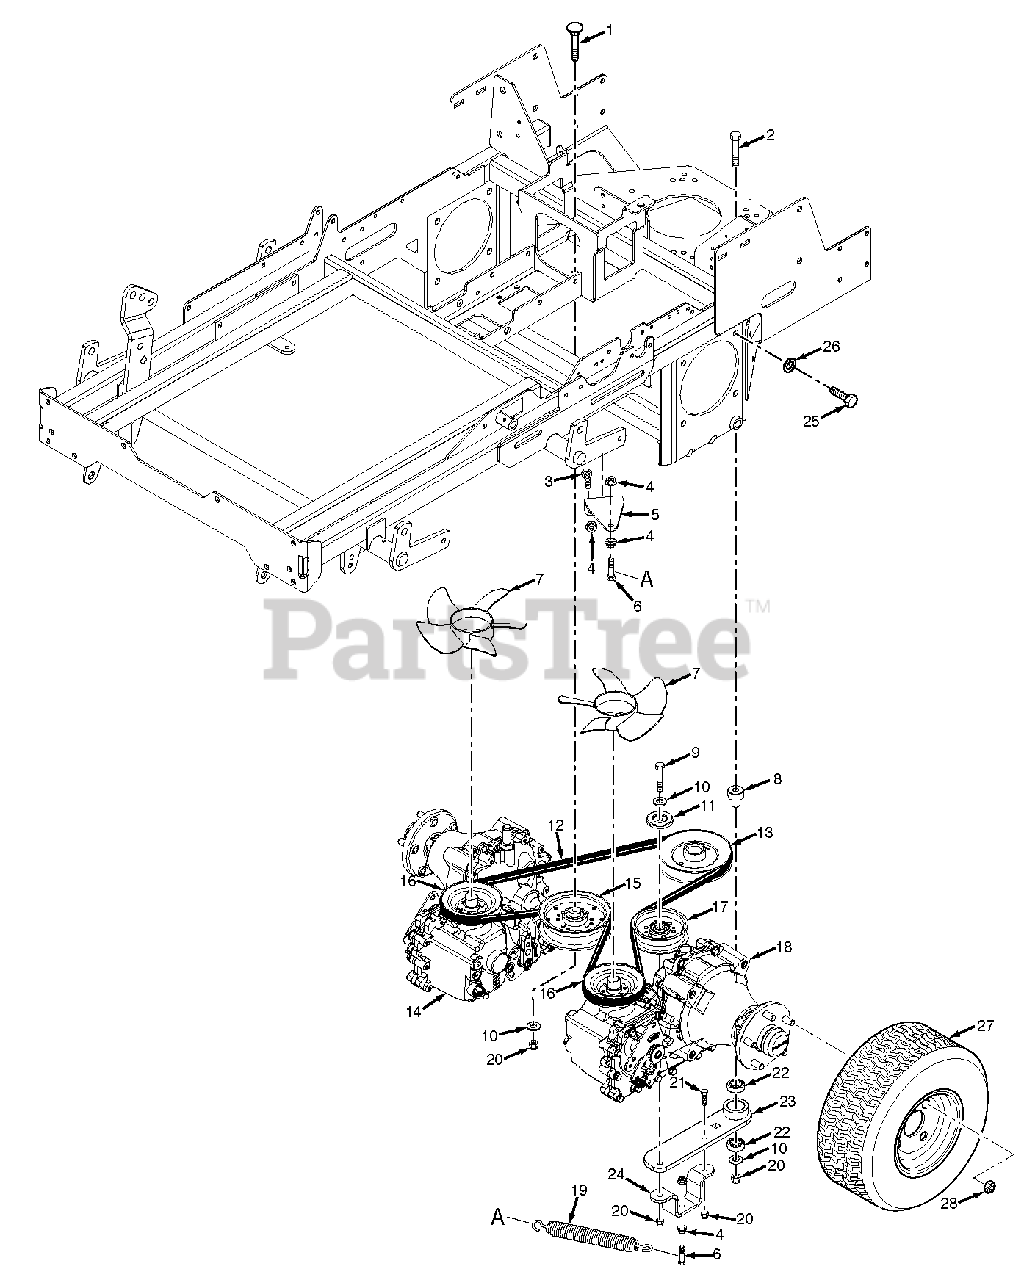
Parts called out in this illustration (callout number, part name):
1	Bolt, Carriage 3/8-16 x 2-1/2"
2	Bolt, Hex Head 3/8-16 x 3"
3	Bolt, Hex Head 3/8-16 x 1"
4	Nut, Serrated Flange 3/8-16
5	Mounting Bracket, Spring - Idler Arm
6	Bolt, Hex Head 3/8-16 x 1-1/2"
7	Kit, Fan / Pulley
8	Pivot, Idler Long
9	Bolt, Hex Head 3/8-16 x 2-3/4"
10	Flatwasher, 3/8-.391 x .938 x .105 HD
11	Dust Shield
12	Belt, Pump Drive
13	Pulley, 5.80" Dia. - 1.125 Bore
14	Transaxle, RH
15	Pulley, 5" Dia. Idler
16	Kit, Fan / Pulley
17	Pulley, 4" Dia. Idler
18	Transaxle, LH
19	Spring, Idler Arm
20	Nut, Elastic Stop 3/8-16
21	Bolt, Hex Head 3/8-16 x 1-1/4"
22	Bearing
23	Idler Arm Assembly (incl. # 22)
24	Mounting Bracket, Idler
25	Bolt, Hex Head 1/2-13 x 1-1/4"
26	Lockwasher, 1/2" Spring
27	Wheel Assembly, 24 x 12-12 4-Ply (5-Hole)
27	Rim w/Valve Stem
27	Tire, 24 x 12-12 4-Ply
28	Lug Nut, 1/2-20
